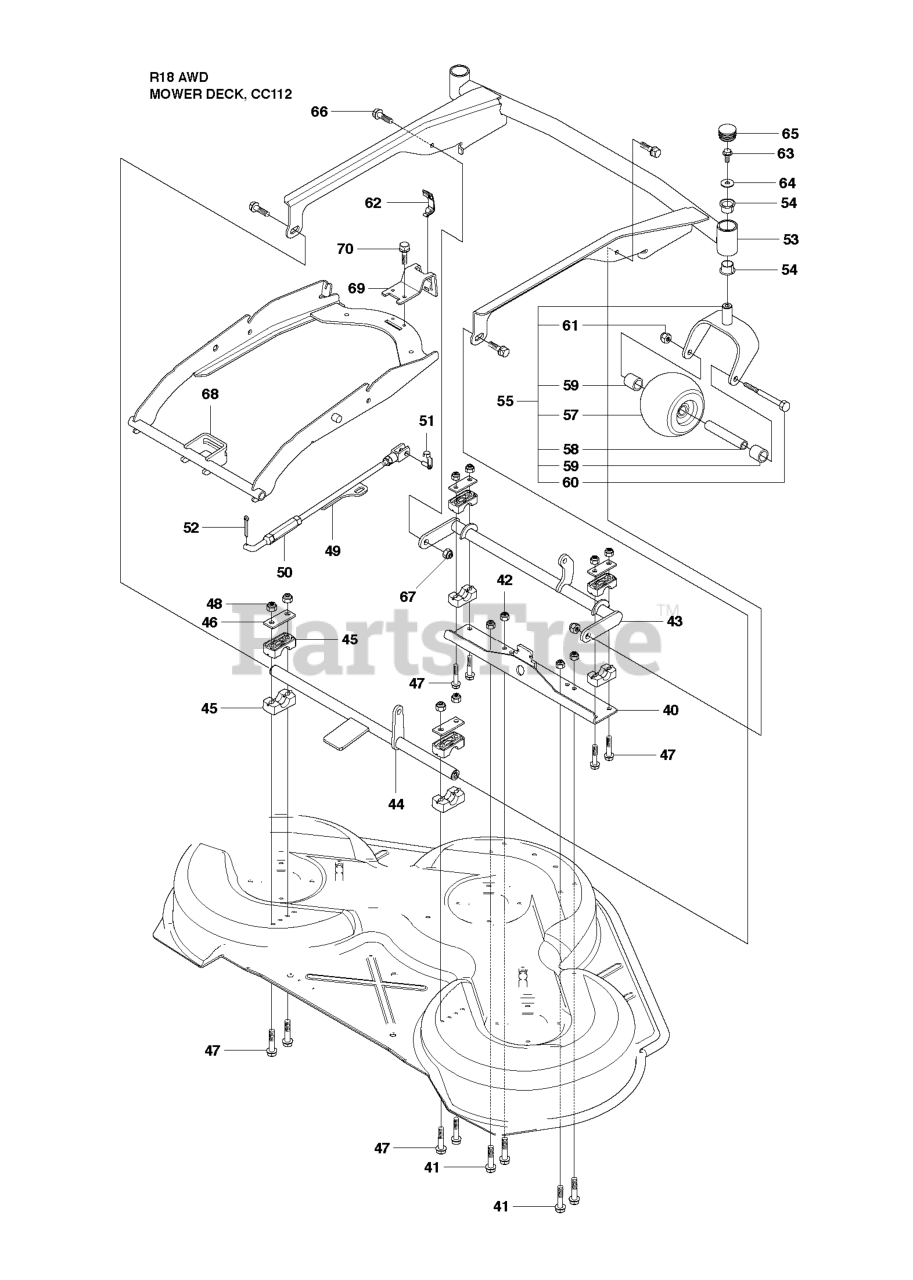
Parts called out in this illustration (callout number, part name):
42	LOCKNUT M8
48	LOCKNUT M8
49	PARALLELL ROD ASSY
50	PARALLEL ROD
51	RETAINER
53	DECK FRAME
55	PIVOT WHEEL ASSY
57	DECK ROLLER, FRONT
61	NUT
62	CLIP GRAY
67	LOCKNUT M8
68	DECK ATTACHMENT
70	SCREW
